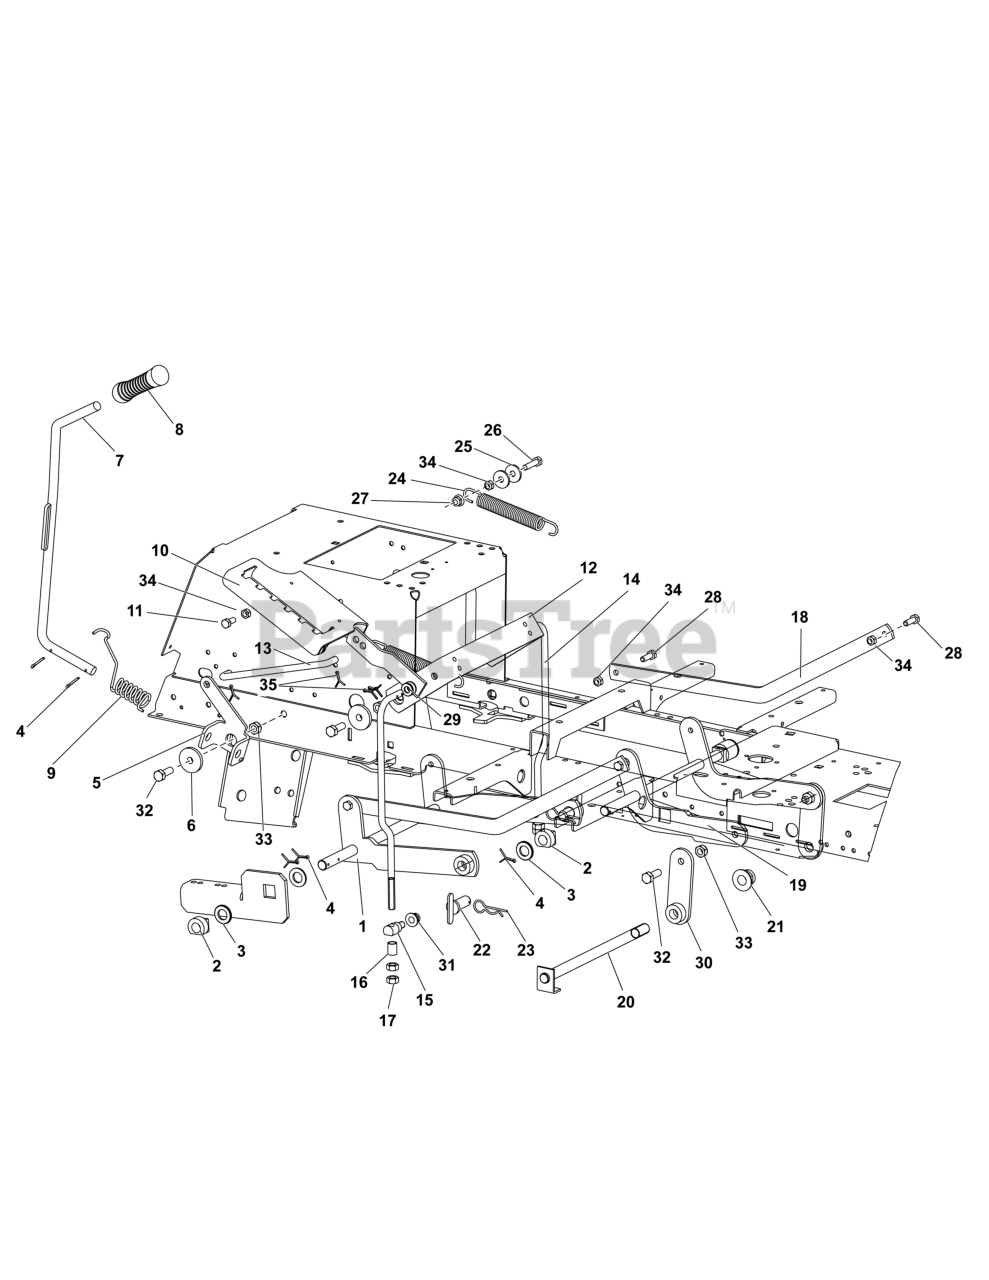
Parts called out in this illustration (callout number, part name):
1	BRACKET, Lifting
8	GRIP, Handle
10	BRACKET, Lifting
13	BAR, Lifting
14	ROD, Lift
18	ROD, Lift
19	BRACKET, Lifting
